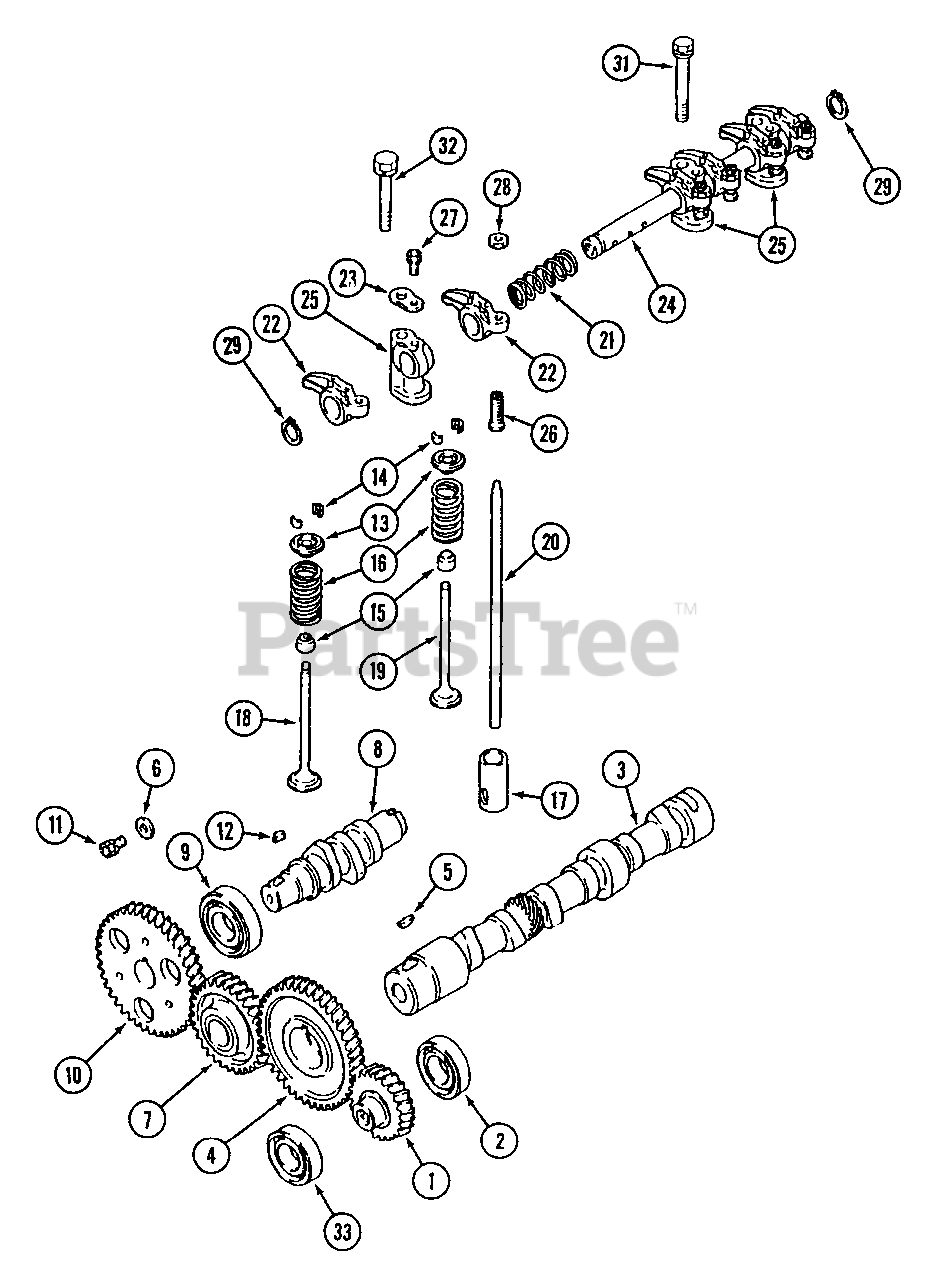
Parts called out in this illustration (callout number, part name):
1	Gear Press Oil Pump
2	Bearing, Ball
4	Gear, Camshaft
5	Key, Woodruff
7	Gear Ass'y., Idler
8	Shaft, Fuel Injection Pump Comp.
9	Bearing, Ball
10	Gear, Fuel Injection Pump Comp.
11	Bolt, w/Washer
13	Retainer, Valve Spring
14	Lock, Valve Spring Retainer
15	Seal, Valve Stem
16	Spring, Valve
17	Tappet
18	Valve, Intake
19	Valve, Exhaust
21	Spring, Rocker Shaft-L.H.
22	Arm, Rocker
23	Washer, Seat
24	Shaft Ass'y. Rocker
25	Stay, Rocker
26	Screw, Adjusting
27	Bolt, w/Washer
28	Nut, Jam
29	Snap Ring
31	Bolt, w/Washer
32	Bolt, w/Washer
33	Bearing, Ball
